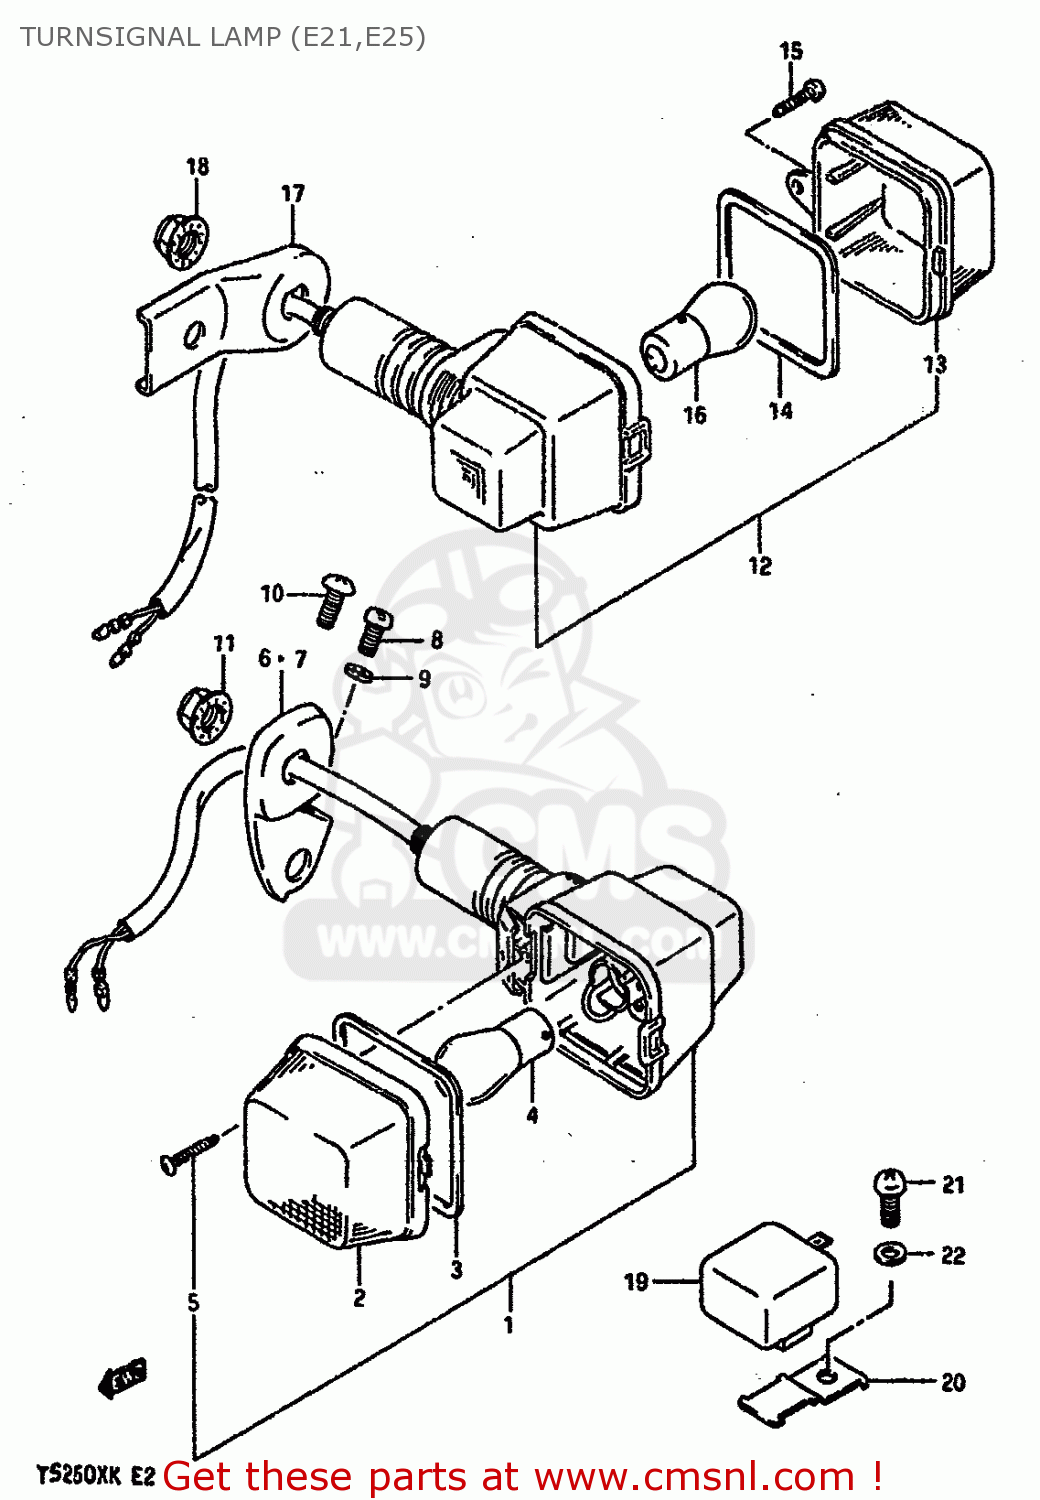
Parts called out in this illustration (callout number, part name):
1	LAMP ASSY,FRONT TURNSIGNAL
2	LENS
3	GASKET (NAS)
4	BULB 12V 21W
5	SCREW
6	BRACKET,FRONT RH
7	BRACKET,FRONT LH
8	SCREW
9	WASHER,LOCK
10	SCREW, FRONT & REAR
11	NUT
12	LAMP ASSY,RR TURNSIGNAL
13	LENS
14	GASKET (NAS)
15	SCREW
16	BULB 12V 21W
17	BRACKET,RR TURNSIGNAL LAMP
18	NUT
19	RELAY ASSEMBLY,TURN SIGNAL
20	BRACKET,RELAY
21	SCREW
22	WASHER,LOCK
